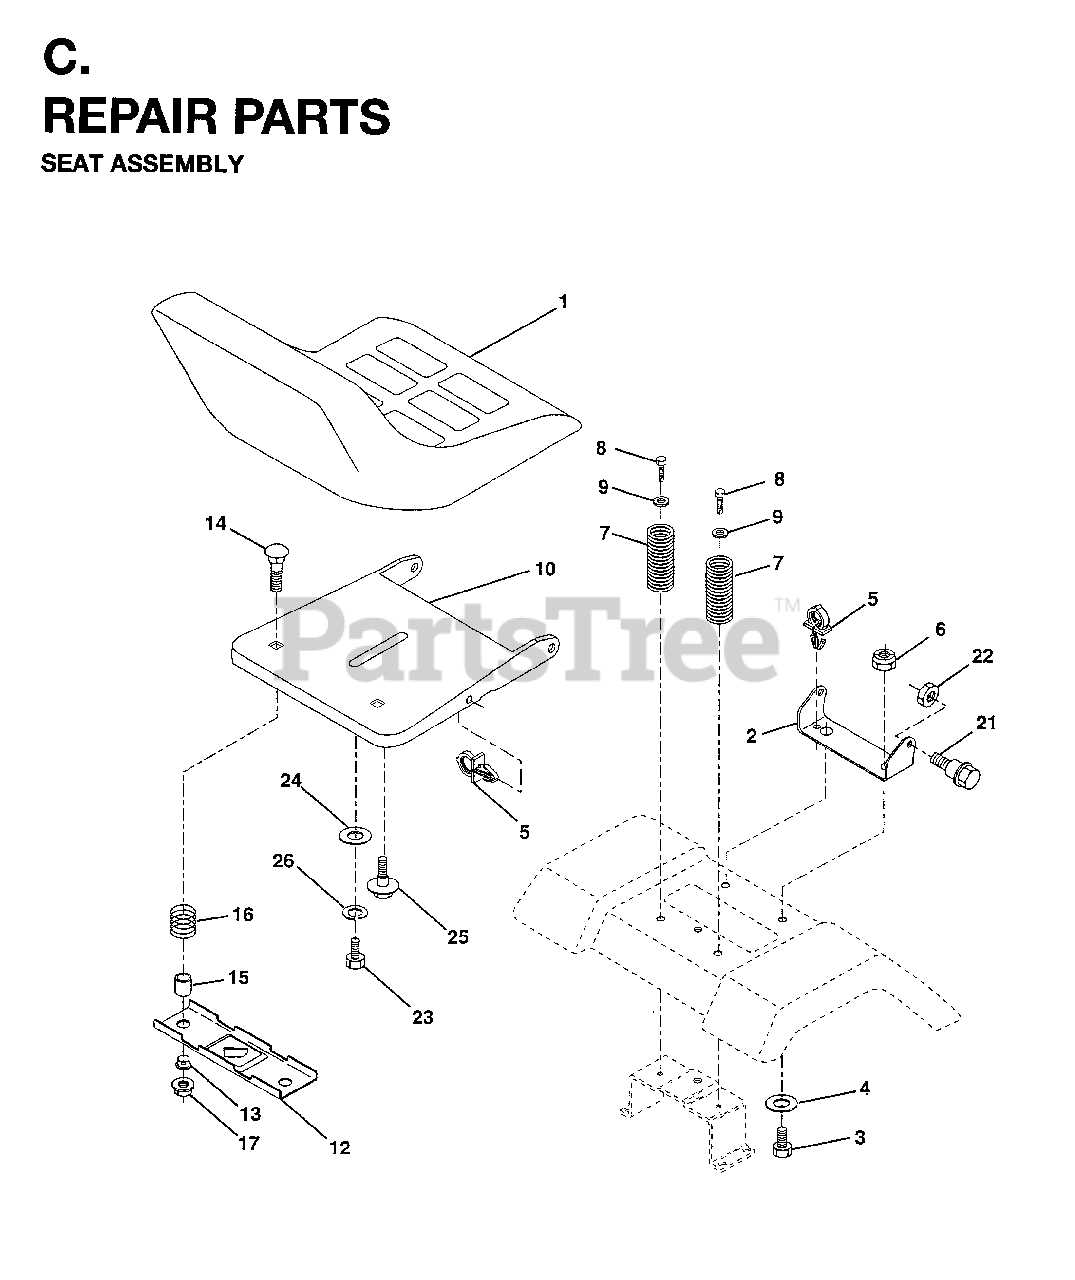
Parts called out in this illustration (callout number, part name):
1	SEAT
2	SEAT PIVOT BRKT
4	WASHER PM
5	PUSH CLIP
6	LOCKNUT
7	SPRING COMPRESSION
9	WASHER
10	SEAT PAN
12	BRKT SWITCH
14	BOLT CARRIAGE 1/4-20X1 3/8
15	SPACER SPLIT
16	SPRING COMPRESSED
17	NUT.CROWNLOCK.1/4
22	LOCKNUT
23	BOLT
25	BOLT,SHOULD
26	LOCKWASHER
